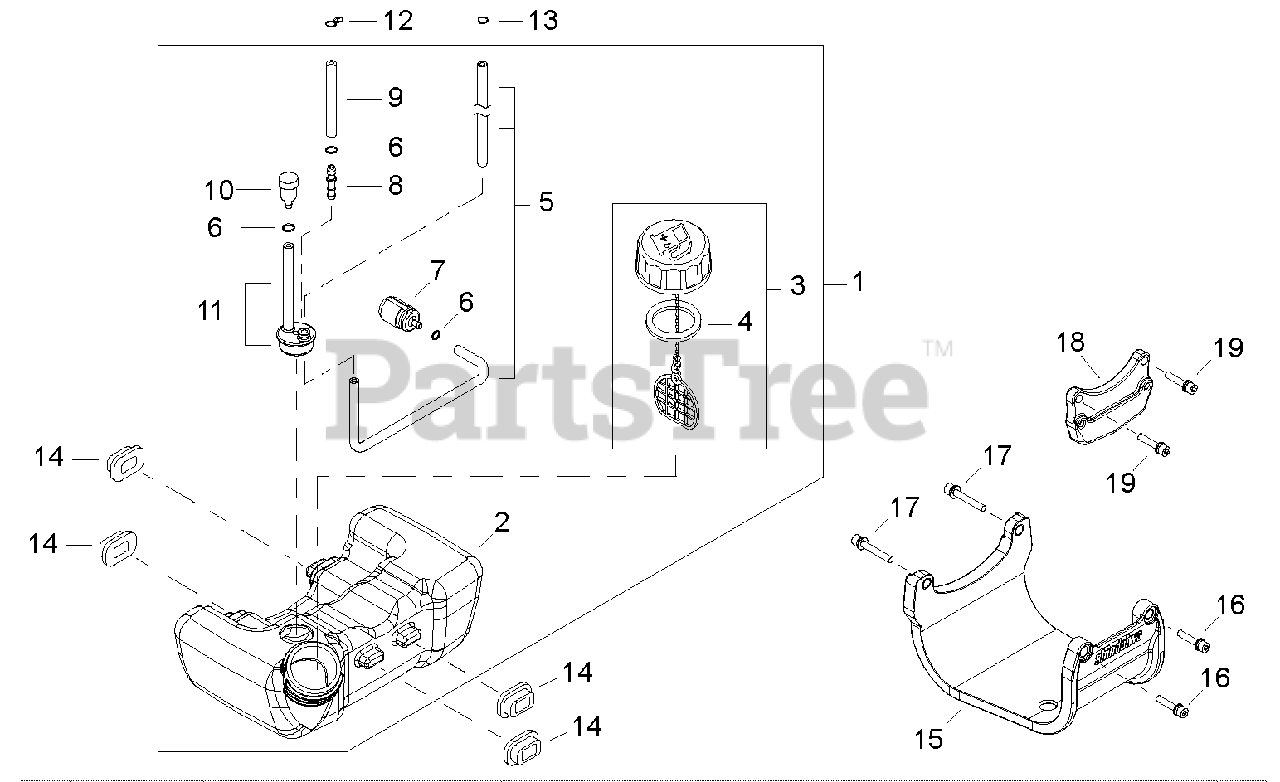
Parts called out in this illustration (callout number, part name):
1	FUEL TANK ASSY
2	TANK, FUEL
3	CAP ASSY
4	GASKET, CAP
5	PIPE - FUEL
6	RING, RETAINING - 6
7	FILTER, FUEL
8	CONNECTOR, PIPE
9	PIPE - RETURN
10	VENT, FUEL TANK
11	VENT PIPE ASSY
12	CLIP - SPRING
13	RING, RETAINING - 6
14	CUSHION, FUEL TANK
15	GUARD, FUEL TANK
16	SCREW - 5X20
17	SCREW - 5X40
18	METAL FUEL TANK BRACKET
19	SCREW - 5X20
